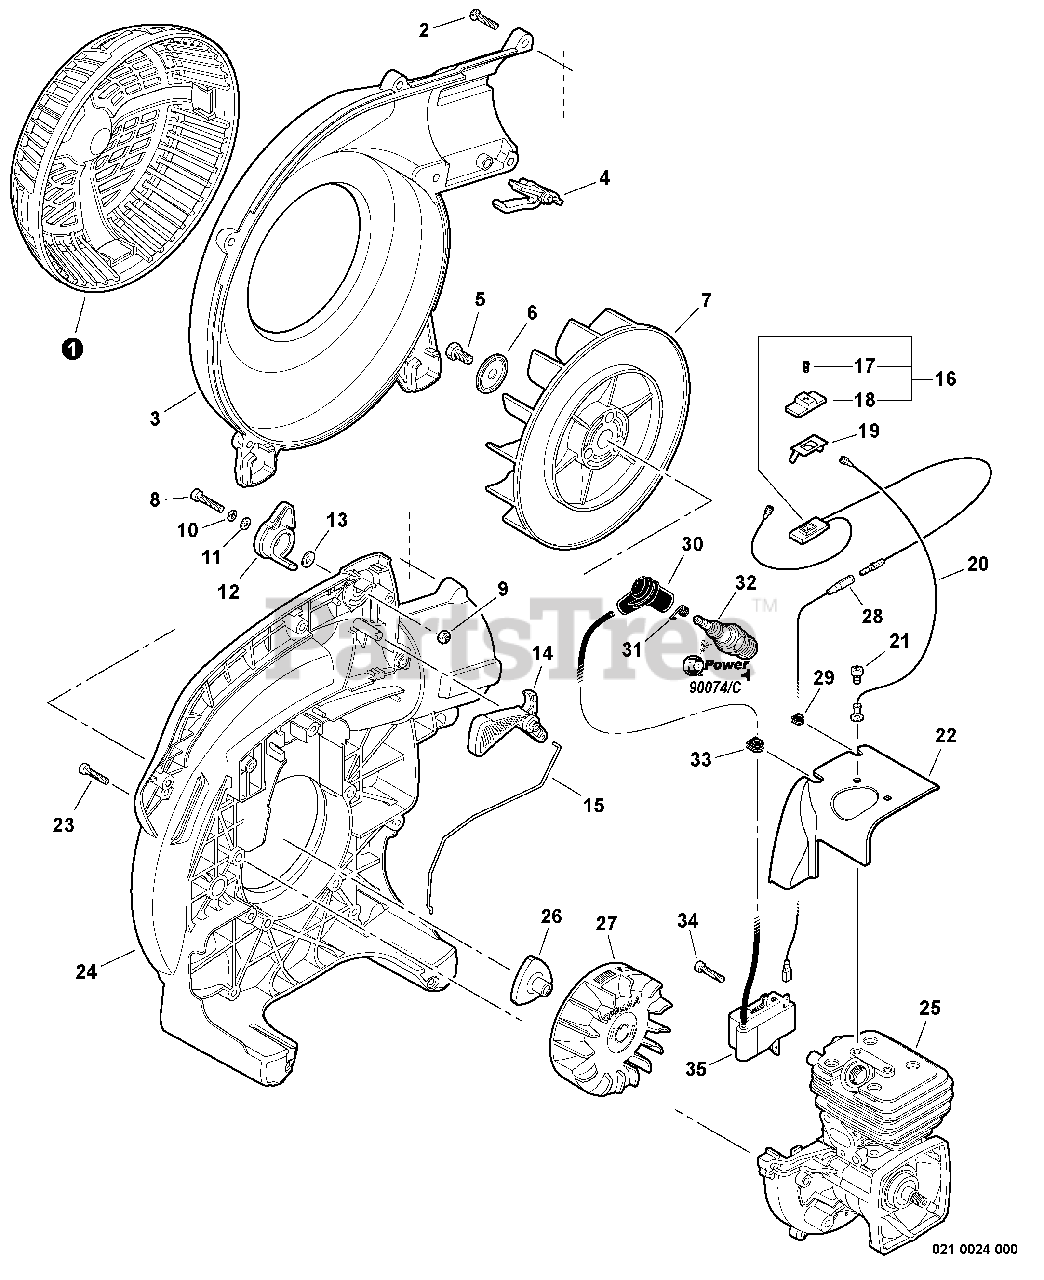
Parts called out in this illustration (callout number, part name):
1	GUARD, DEBRIS
2	SCREW - 5X20
3	COVER, FAN - LEFT
4	LOCK, TUBE
5	BOLT - 8X14
6	WASHER - CUP
8	SCREW - 5X25
9	LOCKNUT - 5
10	LOCKWASHER - 5
11	WASHER - 5
12	LEVER, THROTTLE
13	WASHER - 5
14	TRIGGER, THROTTLE
15	ROD, THROTTLE
16	SWITCH, IGNITION
17	SCREW - 3X10
18	KNOB, SWITCH - ORANGE
19	TERMINAL - GROUND
20	SCREW - 5X8
21	LEAD - GROUND
22	SHIELD, CYLINDER
23	SCREW - 4X20
24	COVER, FAN - RIGHT
25	SHORT BLOCK -- SB1104
26	HUB, FAN
27	FLYWHEEL
28	LEAD - IGNITION
30	CAP, SPARK PLUG
31	TERMINAL, SPARK PLUG CAP
32	SPARK PLUG -- BPM-8Y
32	SPARK PLUG -- BPMR-8Y
34	SCREW - 4X20
35	COIL, IGNITION
36	RePower TUNE-UP KIT
